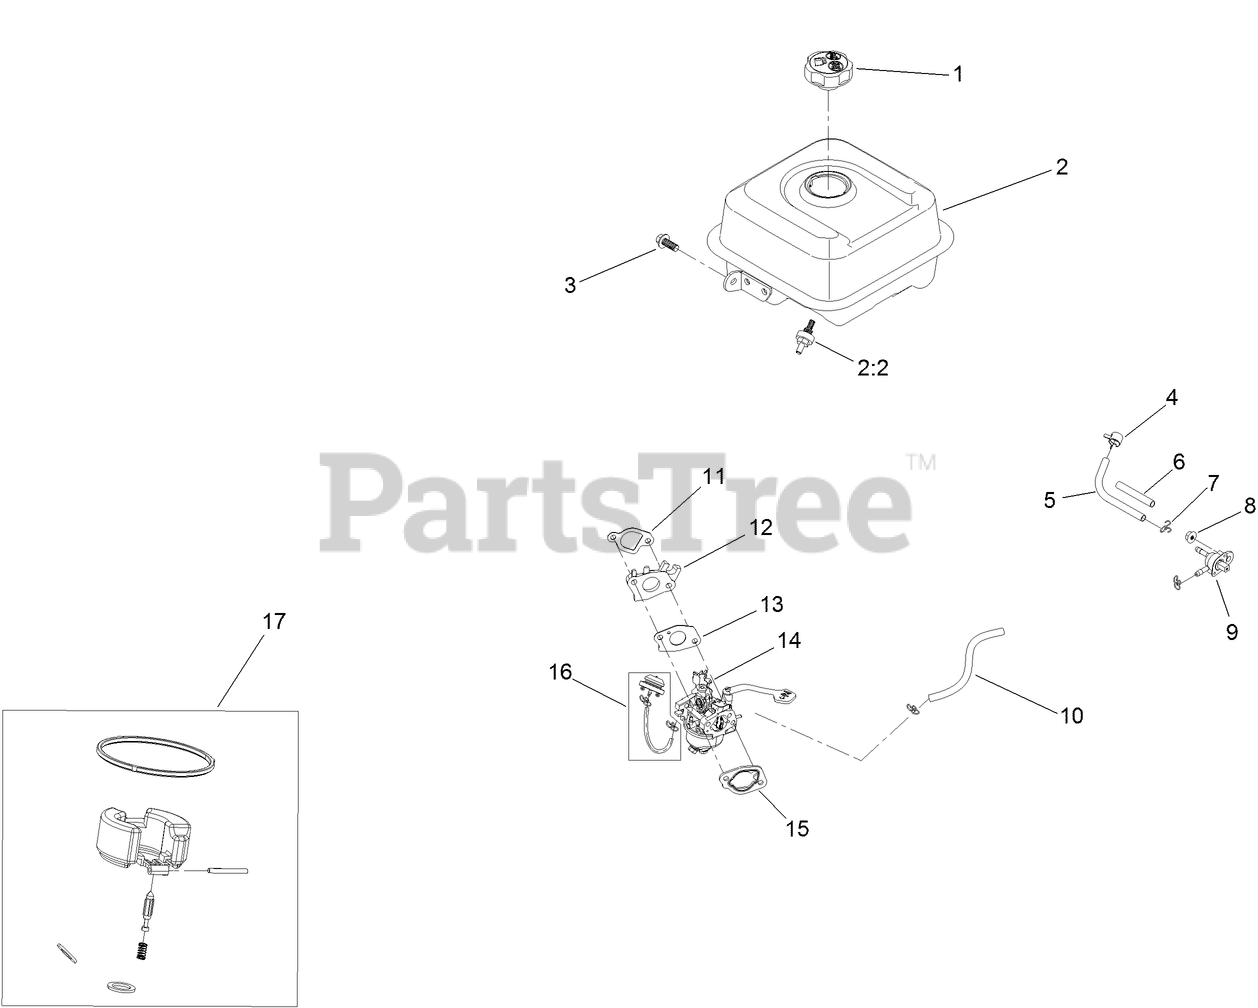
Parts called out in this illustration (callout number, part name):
1	CAP-FUEL
2	FUEL TANK AND FILTER ASM
2:2	FILTER-FUEL
3	SCREW-HHF
4	CLAMP-HOSE
5	HOSE-FUEL
6	SLEEVE-ABRASION
7	CLAMP-HOSE
8	NUT-FLANGE
9	VALVE-FUEL
10	HOSE-FUEL
11	GASKET-CARBURETOR
12	INSULATOR-CARBURETOR
13	GASKET-CARBURETOR
14	CARBURETOR ASM
15	GASKET-CARBURETOR
16	PRIMER KIT
17	INTERNAL CARB SERVICE KIT
